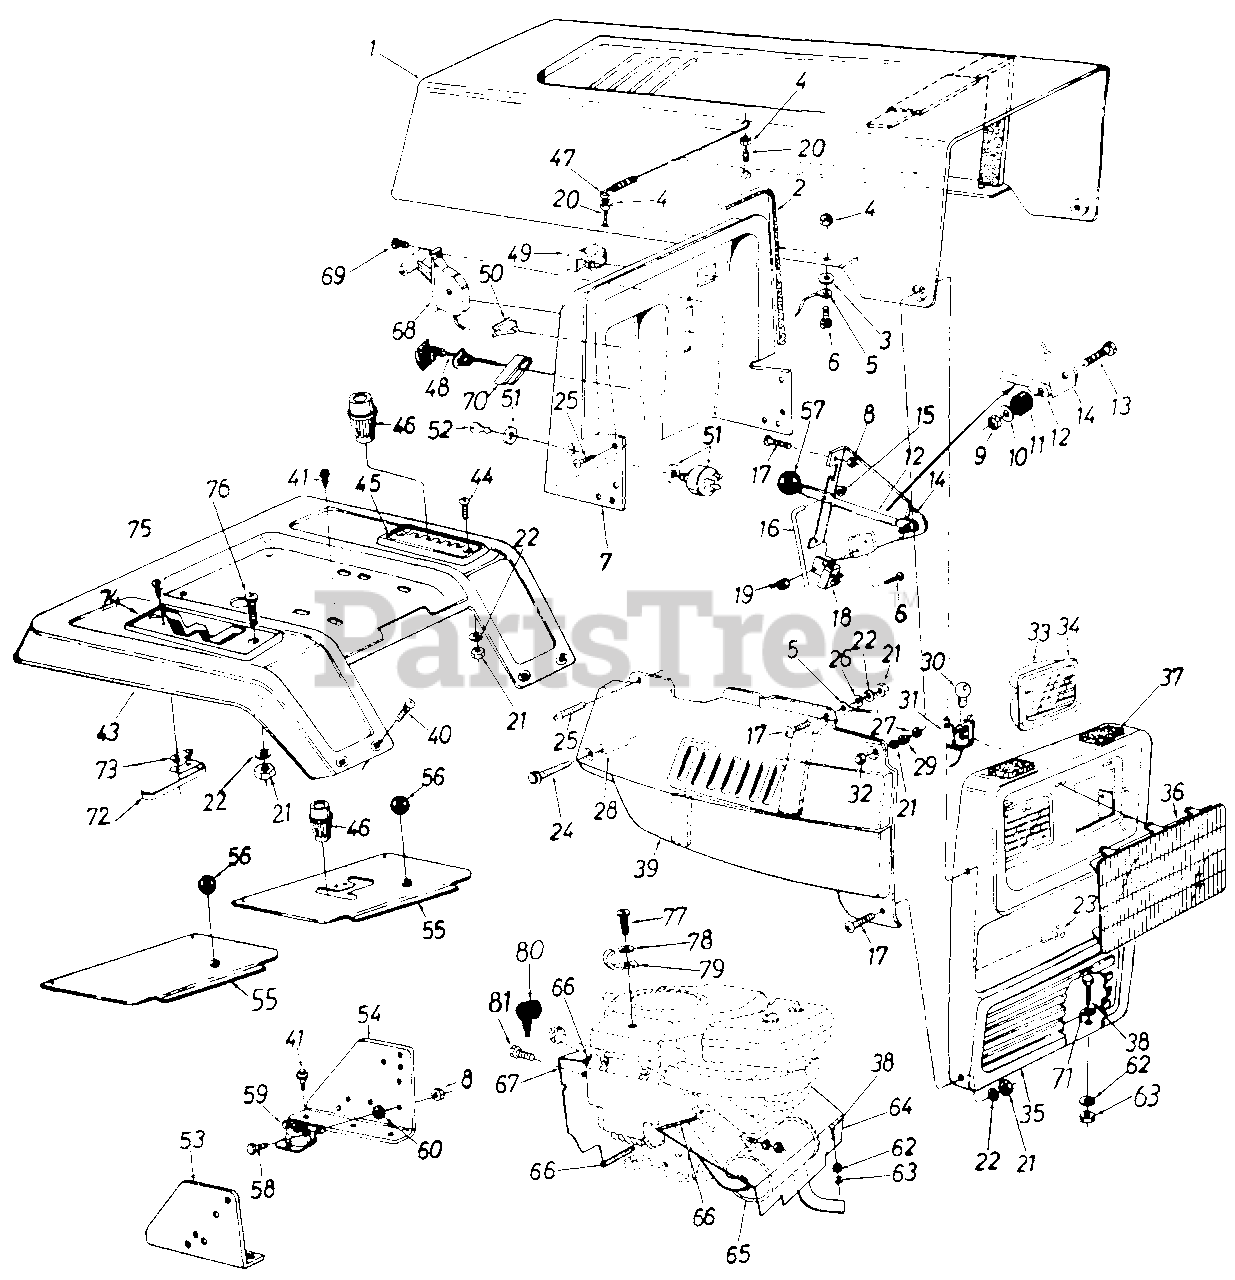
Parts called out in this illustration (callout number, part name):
3	Fl-Wash..20" I.D. x .41" O.D.
4	Hex Sems Nut #10-24 Thd.
5	Hood Stop
6	Truss Mach. Scr. #10-24 x .5" Lg.
9	Hex L-Nut 1/4-20 Thd.
10	Fl-Wash..281" I.D. x .73" O.D.
11	Rubber Washer
12	PTO Lever
13	Hex Bolt 1/4-20 x 1.25" Lg.
14	Deck Clutch Control Brkt.
15	Push Cap
16	Deck Control Rod
17	Truss Mach. Scr. 1/4-20 x .5" Lg.
18	Safety Switch
19	Hex Sems Nut #10-24 Thd.
20	Hex Bolt 10-24 x 1.0" Lg.
21	Hex Nut 1/4-20 Thd.
22	L-Wash. 1/4" I.D.
23	Hex Bolt 1/4-20 x .88" Lg.
24	Hex Wash. TT-Tap Scr. 1/4-20 x 1.75" Lg.
25	Hex TT-Tap Scr. 1/4-20 x .75" Lg.
26	Fl-Wash..25" I.D. x .62"
27	Spr. Wash..39" I.D. x .62"
28	Spacer .26" I.D. x .375"
29	Shld. Spacer .375" Dia. x .125" Lg.
30	Lamp
31	Socket
32	Acorn Nut 1/4-20 Thd.
33	Headlight Housing
34	Headlight Lens
37	Foam Strip
38	Hex Bolt 5/16-18 x .75" Lg.
41	Hex Wash. AB-Tap Scr. 5/16 x .75" Lg.
45	6-Speed Selector Plate
46	Shift Knob
47	Hood Spring
48	Choke Control 46" Lg.
49	Ammeter
50	Light Switch
51	Ignition Switch
52	Ignition Key
56	Ball Knob
57	Knob - Blade Clutch
58	Hex Bolt 1/4-20 x .5" Lg.
59	Solenoid
60	Ext. L-Wash. 1/4" I.D.
62	L-Wash. 5/16" I.D.
63	Hex Nut 5/16-18 Thd.
64	Front Heat Shield
65	Muffler
66	Trim Strip 12" Lg.
67	Rear Baffle
68	Throttle Control Box Ass'y.
69	Truss Mach. AB-Tap Scr. #10 x .5" Lg.
70	Retainer Clip
71	Fl-Wash..344" I.D. x 1" O.D. (Hdn.)
72	Spring Switch
73	Insulator Nut Plate
74	Forward/Reverse Index Brkt.
75	Hex Wash. Hd. AB-Tap Scr. 08 x .5" Lg.
76	Truss Mach. Scr. 1/4-20 x .75" Lg.
77	Truss Mach. B-Tap Scr. #10 x .5" Lg.
78	Flk-Wash..188" I.D. x .438" O.D.
79	Clamp
81	Hex Wash Hd. TT-Tap Scr. 1/4-20 x .5" Lg.
17426A-0638	FENDER-RR - MTD/TROY-BILT RED (0638)
17426A-0648	FENDER-RR - TECH GRAY (0648)
17459-0638	PANEL-SIDE-LH - MTD/TROY-BILT RED (0638)
